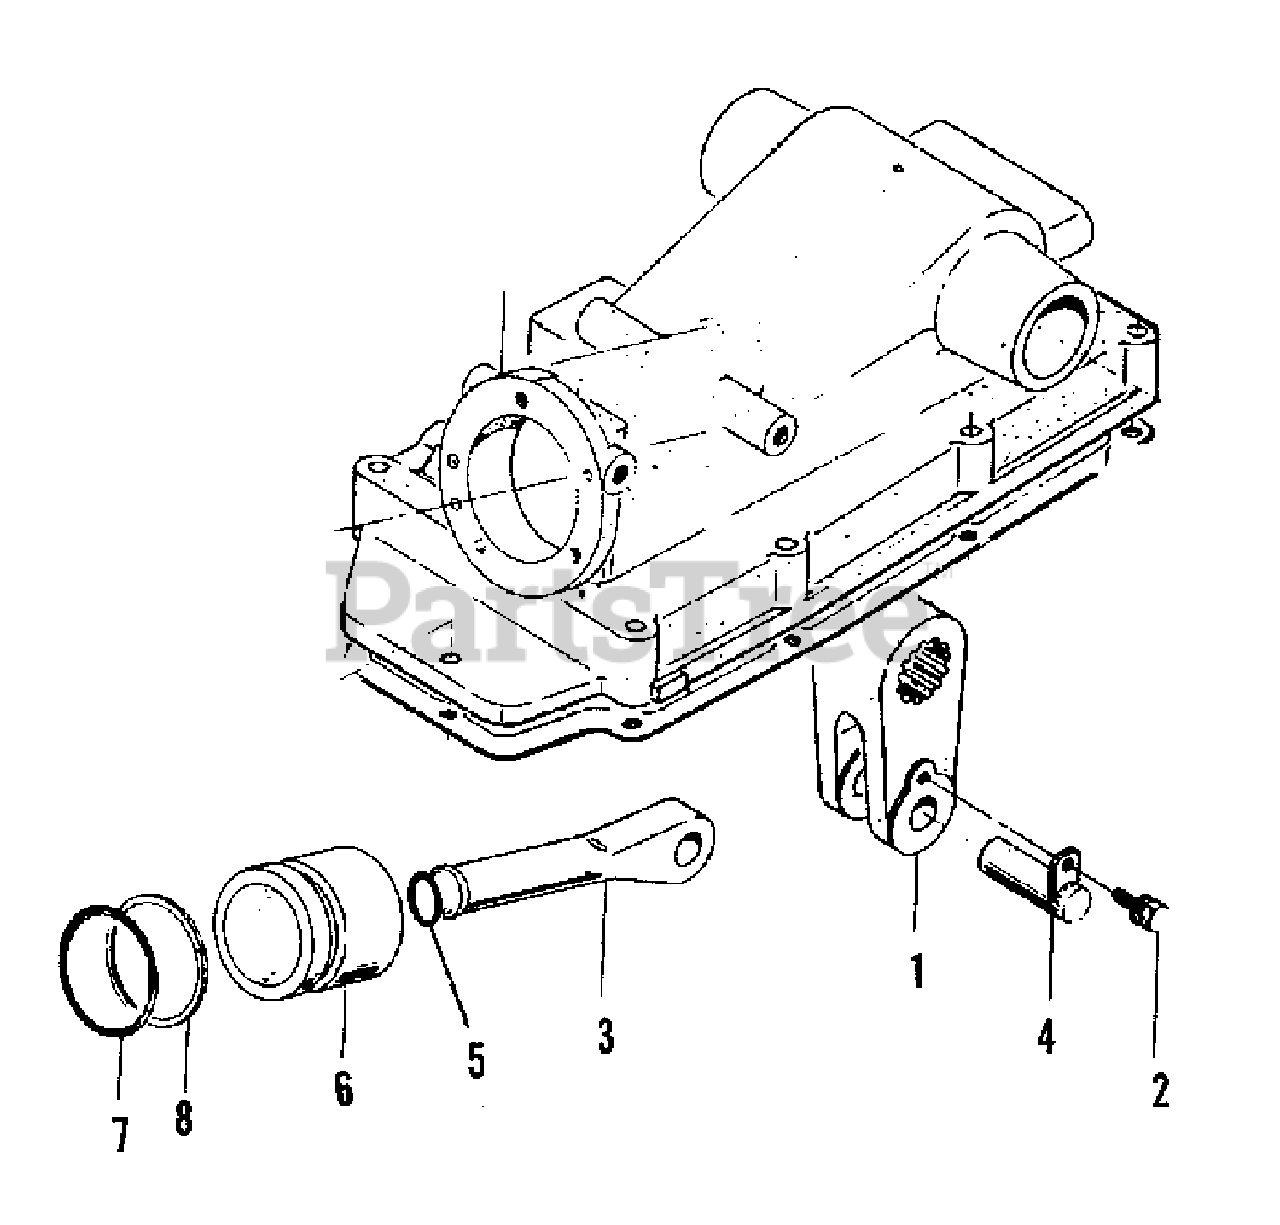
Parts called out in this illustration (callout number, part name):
1	ARM, lever
2	CAPSCREW, M10 x 20
3	ROD, push
